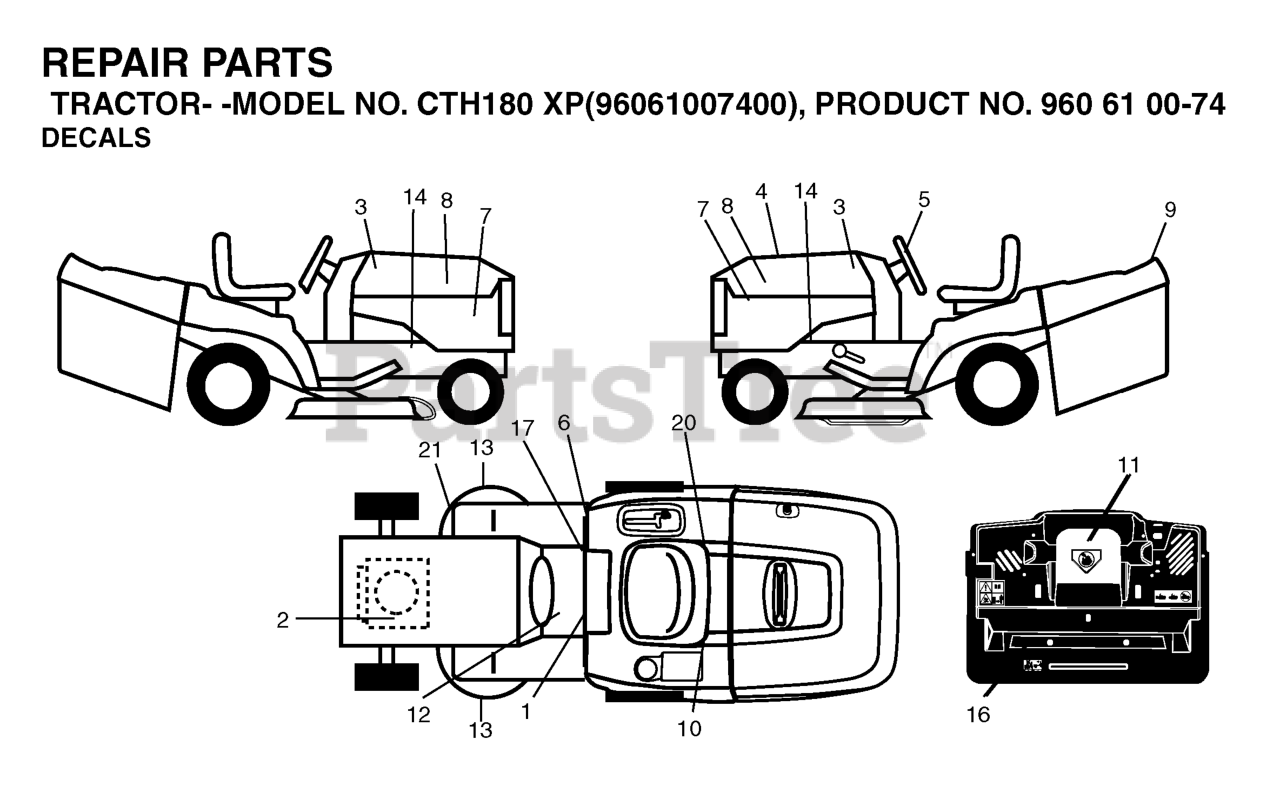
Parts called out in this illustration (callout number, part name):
1	LABEL
2	DECAL
5	DECAL.STEERING.HUSQ.BLUE
6	Decal, Fender 100 DB/CE
8	DECAL.HOOD.HUSQVARNA.INTERNATI
10	DECAL BTRY SYMBOLS
11	DECAL.INTERNATIONL.CUTFINGER
12	DECAL
16	DECAL
17	DECAL PARK BRAKE
20	DECAL.BYPASS.FENDER.CRD.LT.YT
